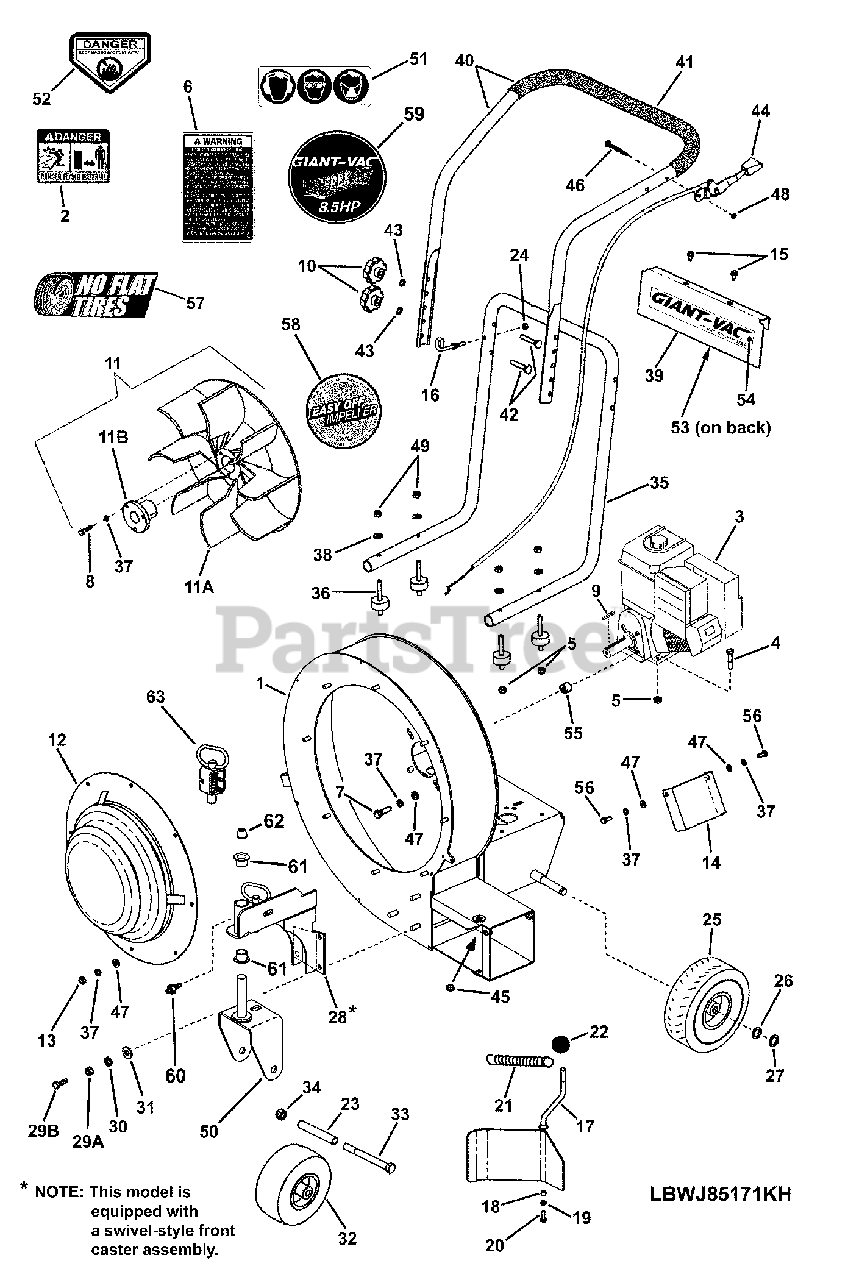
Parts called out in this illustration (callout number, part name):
1	WELDMENT, Housing- 85KWJ & 13KWJ
2	DECAL, Thrown Objects, Large
4	SCREW, 5/16-18 x 1-1/2 Hex Head Cap, GR 5
5	NUT, 5/16-18 Hex Flange Lock, GR 5
6	DECAL, Warning- Leaf Blower
7	SCREW, 5/16-24 x 1-3/4" Hex Head Cap, GR 5
8	SCREW, 5/16-18 x 1-1/4", Hex Head Cap, GR 5
9	KEY, 1/4" Square x 2"
10	KNOB, Fluted- Folding Handles (5/16-18 thread)
11	ASSEMBLY, 17" 8 Curved Blade Impeller
11A	IMPELLER, Cast, 17" O.D.
11B	HUB, Taper-Lok, Type 1 (2.938 OAL)
12	WELDMENT, Intake Baffle- WJ- 17"
13	NUT, 5/16-18 Hex, GR 5 or B
14	DEFLECTOR, Side Air- WJ- 17"
15	SCREW, 5/16-18 x 5/8" Hex Washer Self-Tap
16	GUIDE, Rope (1/4-20 thread)
17	** WELDMENT, Door Discharge- WJ- 17"
18	BUSHING, Steel .250 ID x .375 OD x .25 Long
19	WASHER, 1/4" Split Lock
20	SCREW, 1/4-20 x 3/4" Hex Head Cap, GR 5
21	SPRING, Extension
22	KNOB, Ball Hand Lever- 3/8-16 Metal Insert
23	TUBE, Front Wheel- Extreme
24	NUT, 1/4-20 Hex Center Lock, GR 5 or B
25	ASSY., Wheel & Tire 410/350-4 "Flatfree"
26	WASHER, .64 x .99 x .05 Flat
27	RING, External Retaining (TRU1500-62)
28	***WELDMENT, Swivel Caster Arm
29A	NUT, 3/8-16 Hex, GR 5 or B
29B	SCREW, 3/8-16 x 1" Hex Head Cap, GR 5
30	WASHER, 3/8" Split Lock
31	WASHER, 3/8" Flat
32	ASSEMBLY, Tire & Wheel 9 x 350-4 "Flatfree"
33	BOLT, 1/2-13 x 5" Hex Head Cap
34	NUT, 1/2-13 Hex Center Lock, GR 5
35	HANDLE, Lower Folding- Wide- Blower
36	MOUNT, Vibration (5/16-18 thread- both ends)
37	WASHER, 5/16" Split Lock
38	WASHER, 5/16" Curved
39	DASH PANEL, Blower- Wide
40	ASSY, Upper Handle & Grip- Wide
41	GRIP, 1.0 x 21-1/2" Foam
42	BOLT, Curved Head Square Neck 5/16-18 x 2" GR 2
43	WASHER, 5/16" Internal Tooth Lock
44	THROTTLE CONTROL, 35.24/3.00, Kohler
45	BUSHING, Flanged .375 x .500 x .25 (.625 x .063 Flange)
46	SCREW, 1/4-20 x 2" Hex Head Cap, GR 5
47	WASHER, .34 x .69 x .08 Flat
48	NUT,1/4-20 Hex Nyloc
49	NUT, 5/16-18 Hex Nyloc
50	WELDMENT, Swivel Caster
51	DECAL, Personal Protection
52	DECAL, Danger, Cut Finger
53	DECAL, GIANT-VAC (Small)
54	DECAL, GIANT VAC
55	SPACER, .375 I.D. x .750 O.D. x .750
56	SCREW, 3/8-16 x 1" Hex Head Cap, GR 5
57	DECAL, No Flat Tire
58	DECAL, Easy Off Impeller
59	DECAL, 8.5HP Whisper Jet
60	LUBE FITTING
61	BUSHING, .75 I.D. Flange
62	CAP, Push Plastic
63	ASSY, 5/8" Spring Latch
